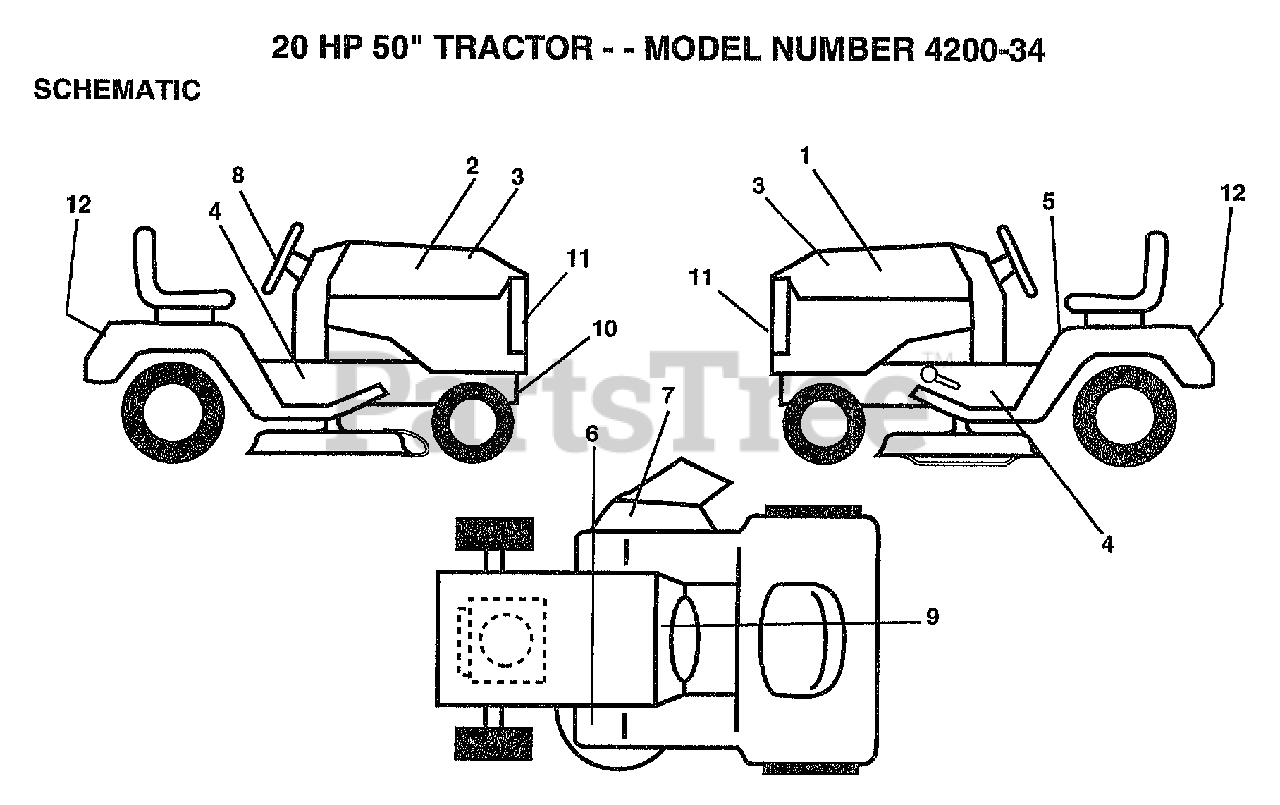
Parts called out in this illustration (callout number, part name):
1	HOOD DECAL LH
3	NAMEPLATE LOGO
4	DECAL.CHASSIS
5	DECAL
7	DECAL WARING
11	GRILL DECAL
12	REFLECTOR-TAIL YT
